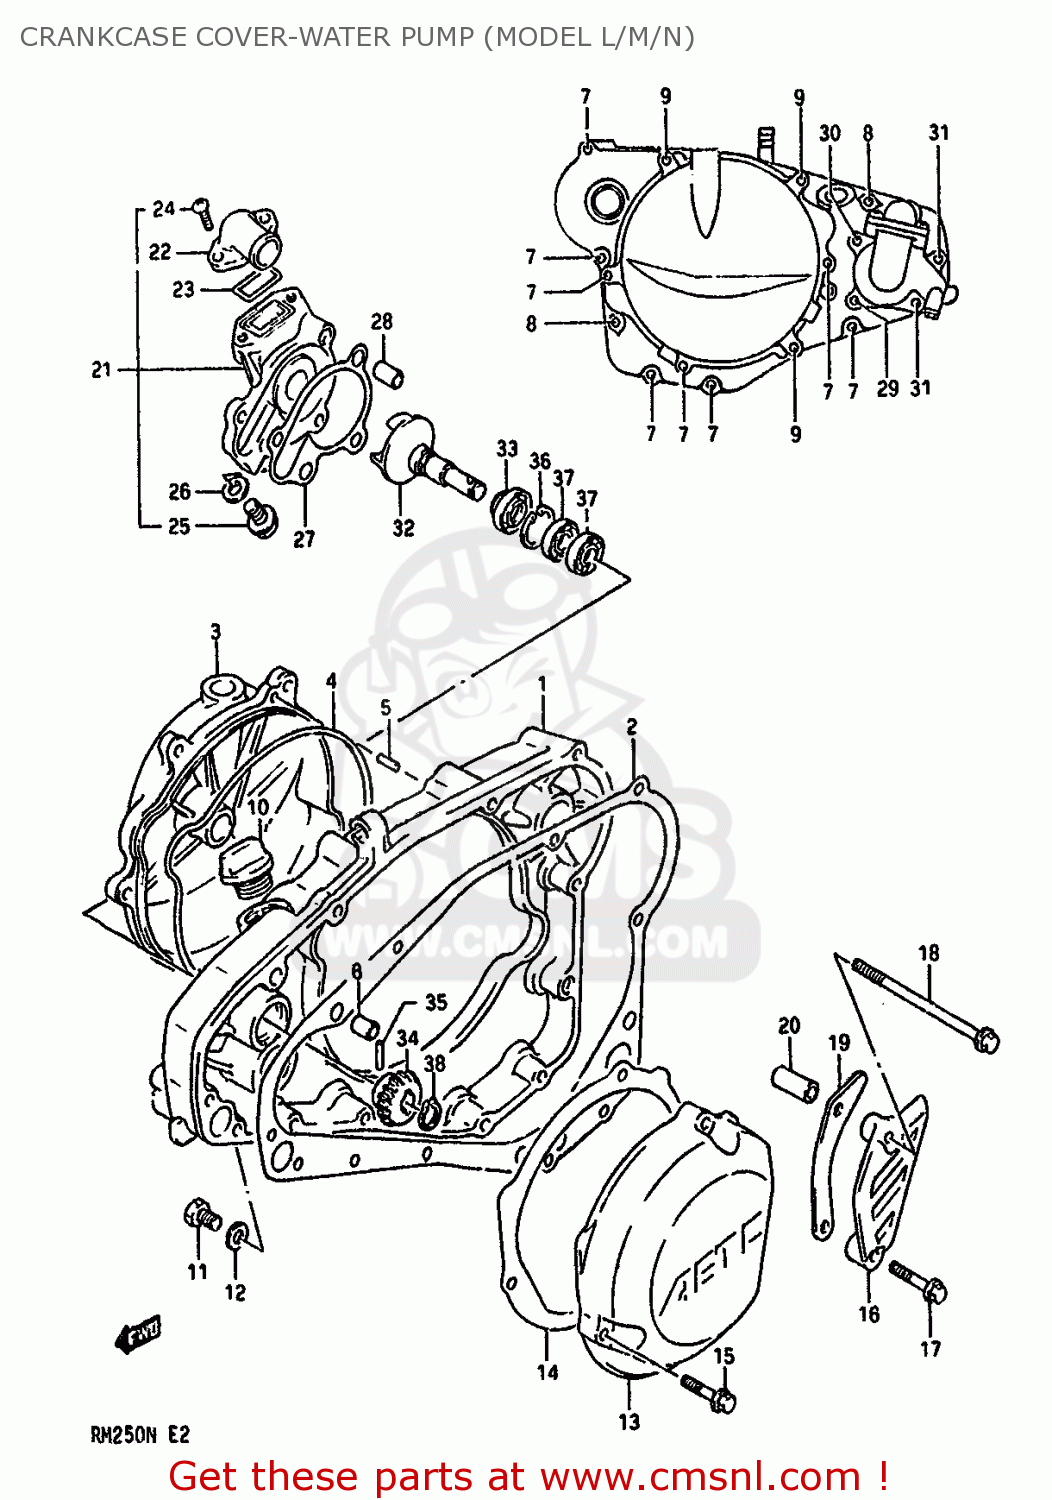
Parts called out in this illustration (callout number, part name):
1	COVER,CLUTCH
2	GASKET,CLUTCH COVER (NAS)
3	COVER,CLUTCH,OUTER
4	O RING,CLUTCH COVER OUTER
5	PIN
6	PIN
7	BOLT
8	BOLT
9	BOLT
10	PLUG SET
11	SCREW(6X10)
12	GASKET(6.2X11X1).2 (NAS)
13	COVER
14	GASKET,MAGNETO COVER (NAS)
15	BOLT
16	COVER,SPROCKET
17	BOLT
18	BOLT 6X95
19	PLATE,FR CHAIN GUIDE(13T)
20	SPACER(6.5X10.5X25)
21	CASE,WATER PUMP
22	CONNECTOR
23	O RING,WATER PUMP CONNECTOR
24	SCREW
25	BOLT,BLEEDER
26	WASHER
27	GASKET,WATER PUMP CASE (NAS)
28	PIN
29	BOLT
30	BOLT
31	BOLT
32	IMPELLER,WATER PUMP
33	SEAL,WATER PUMP OIL
34	GEAR,WATER PUMP DRIVEN
35	PIN(3X13.8)
36	CIRCLIP
37	BEARING
38	CIRCLIP,10MM
